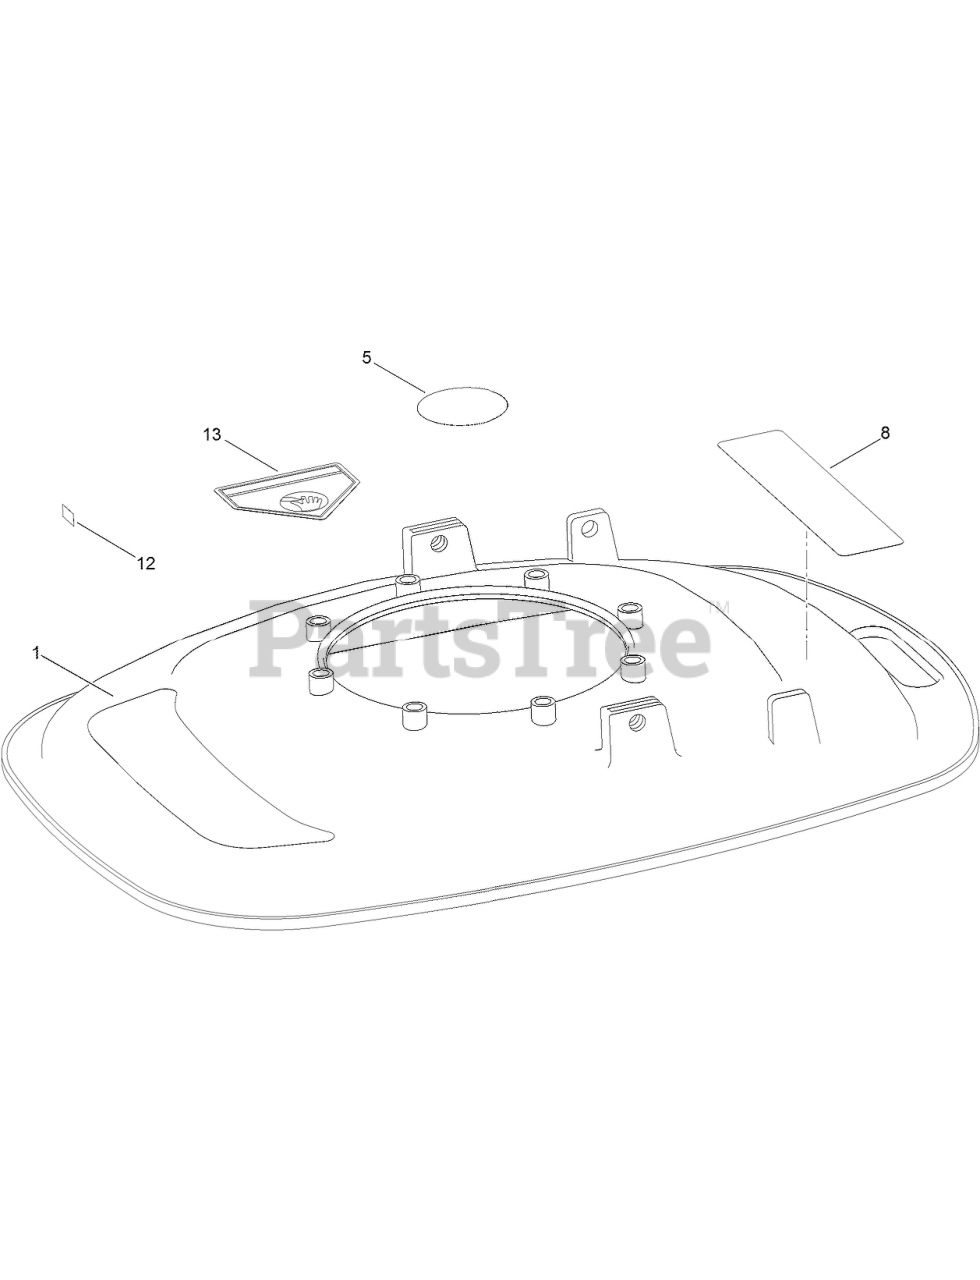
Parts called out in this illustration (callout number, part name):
1	DECAL-HOVER PRO
5	DECAL-ENGINE
8	DECAL-WARNING
12	DECAL-STOP
13	DECAL-DANGER
